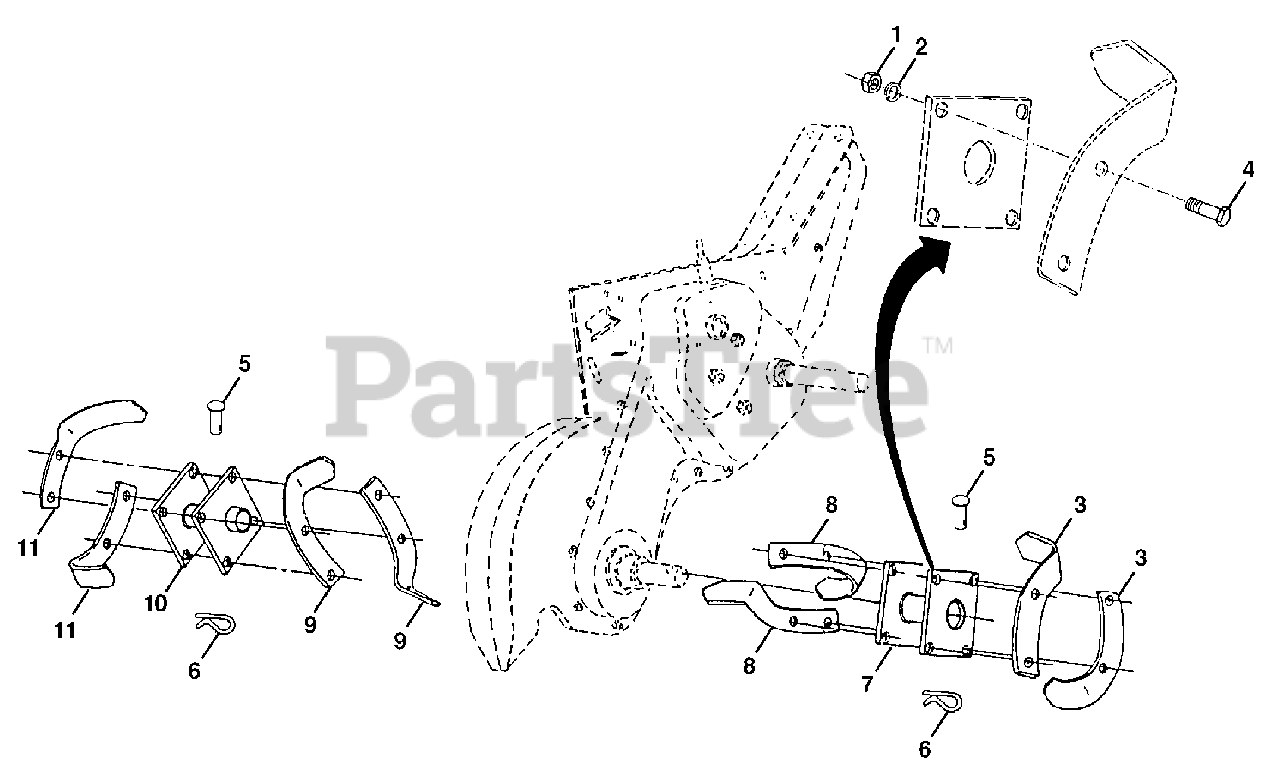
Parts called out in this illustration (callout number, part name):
1	Nut, Hex 3/8-24
2	Washer, Lock 3/8
3	Tine, Outer, R.H.
4	Bolt, Hex 3/8-24 x 1
5	Pin, Shear
6	Clip, Hairpin
7	Assembly, Hub and Plate, R.H.
8	Tine, Inner, R.H.
9	Tine, Inner, L.H.
10	Assembly, Hub and Plate, L.H.
11	Tine, Outer, L.H.
